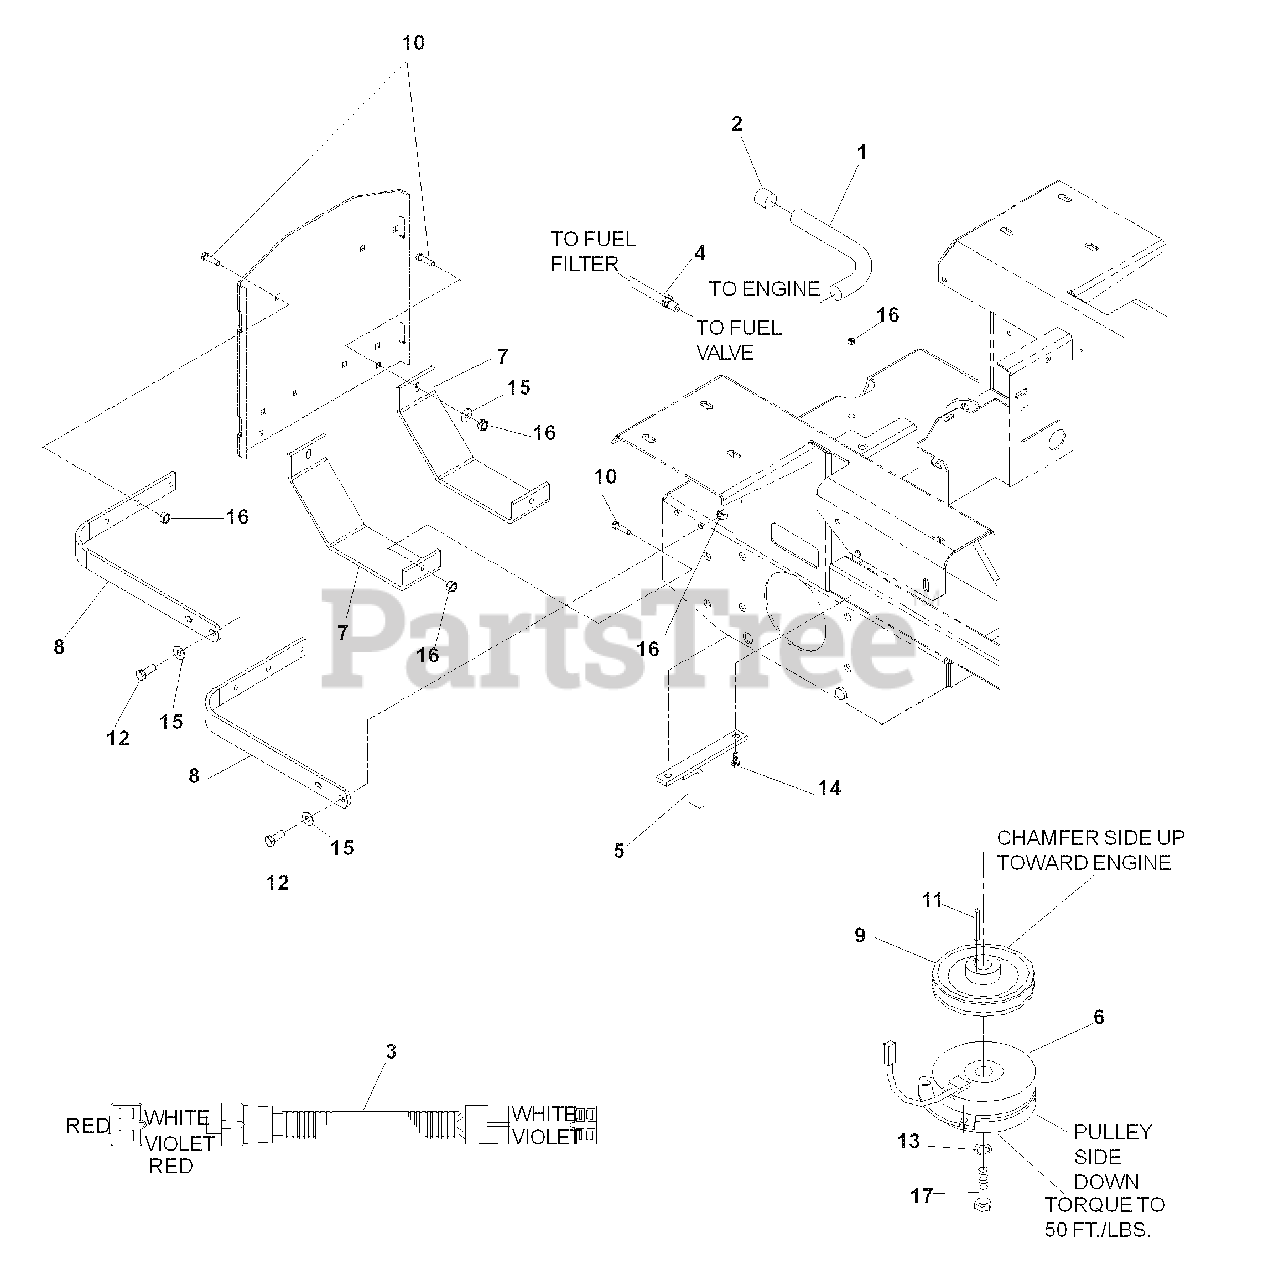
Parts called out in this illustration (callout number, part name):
1	HOSE-DRAIN
3	PIGTAIL, KOHLER
4	FUEL LINE, 13"
5	CLUTCH TIE DOWN
6	CLUTCH MODELS 968999307,968999308, 968999332, 968999528
7	SKID PLATE
10	RHSNB, 5/16-18 x 1
11	KEY, 1/4 SQ x 1 1/4
12	HCS, 5/16-18 x 1
13	LOCKWASHER, 7/16
14	HCS, 5/16-18 x 1 3/4
15	WASHER, 5/16
16	NUT, 5/16-18, NYLOC
17	HCS, 7/16-20 x 2 1/2
